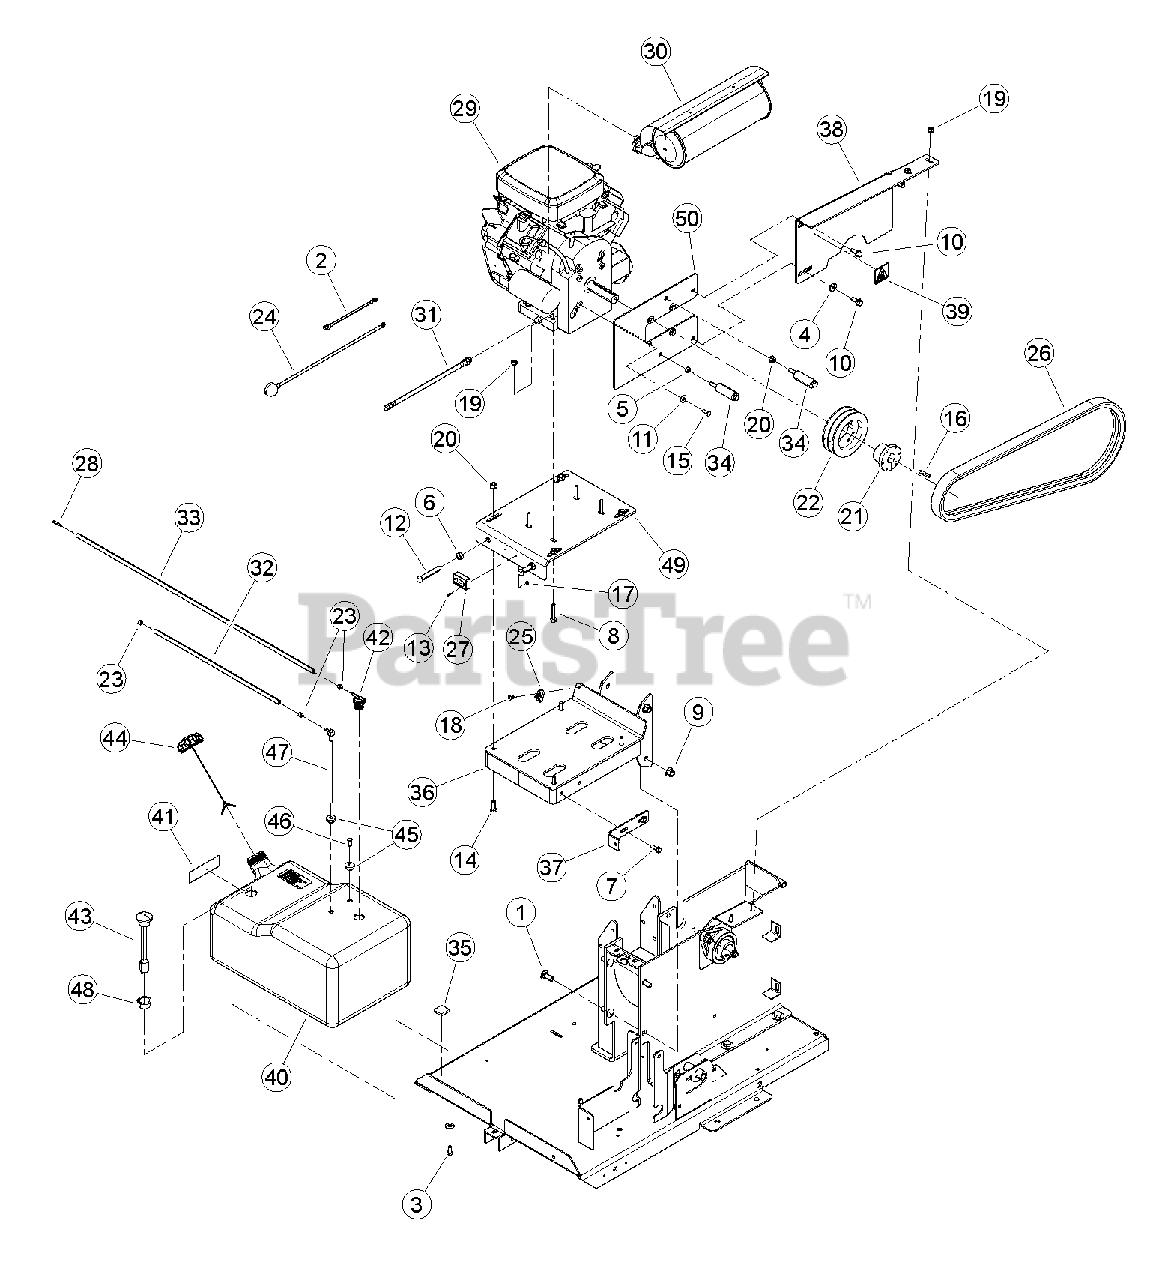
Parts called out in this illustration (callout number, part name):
1	BOLT, 1/2-13 X 1-1/4 GR5 CRG
2	CABLE, 24" NEG (R/R)
3	BOLT, 3/8 X 3/4 GR5 HEX CAPSCREW ZP
4	WASHER, 3/8 FLAT
5	NUT, 3/8" HEX NC ZP
6	NUT, 1/2 NC ZP JAM
7	BOLT, 5/16 X 1 FLANGE NC
8	BOLT, 5/16 X 2 FLANGE NC
9	NUT, 1/2-13 NYLOCK FLANGE
10	BOLT, 3/8 X 1 FLANGE NC
11	WASHER, 5/16 FLAT
12	SETSCREW, 1/2 X 3 SQ HD 1/2 DOG PT
13	SCREW, #6-32 X 3/4 PAN PHP ZP
14	BOLT, 3/8-16 X 1-1/4 GR5 CRG
15	BOLT, 5/16-24 X 3/4" GR5 HHCS ZP
16	KEY, 1/4 SQ X 1-1/2 LG PLAIN
17	NUT, #6-32 NYLON LOCK ZP
18	RIVET, AL BLIND 1/4 X 3/4 DOME HEAD
19	NUT, 5/16-18 NYLOCK FLANGE
20	NUT, 3/8-16 NYLOCK FLANGE
21	BUSHING, SD 1-1/8"
22	SHEAVE, 2B5.2 SDS
23	CLAMP, 15/32 SPRING
24	CABLE, 33" POS (R/R WITH BOOT)
25	CLAMP, CABLE MOUNT
26	BELT, 2BRP67
27	METER, TACH/HOUR
28	FITTING, 3/16" X 1/4" VACUUM
29	ENGINE, 23 HP BRIGGS (FOR SERVICE SEE ENGINE OWNER'S MANUAL OR NEAREST BRIGGS & STRATTON INDUSTRIAL ENGINE DEALER)
30	MUFFLER, BRIGGS 23 HP OIL FILTER SIDE (FOR SERVICE SEE ENGINE OWNER'S MANUAL OR NEAREST BRIGGS & STRATTON INDUSTRIAL ENGINE DEALER)
31	HOSE ASSEMBLY, CRANKCASE DRAIN
32	HOSE, 20" FUEL LINE
33	HOSE, 38" FUEL LINE
34	WELDMENT, BELT GUIDE
35	PAD, FOAM FUEL TANK DAMPER
36	WELDMENT, ENGINE BASE
37	WELDMENT, SHIELD BRACKET
38	ASSEMBLY, BELT GUIDE W/ DECAL
39	DECAL, SHIELD DANGER ISO
40	ASSEMBLY, FUEL TANK
41	DECAL, UNLEADED GASOLINE
42	VALVE, ROLL OVER
43	GAUGE, FUEL LEVEL KELCH 100
44	CAP, NON-VENTED EPA/CARB APPROVED
45	GROMMET, TANK FITTING
46	PLUG, TANK VENT
47	FITTING, TANK FUEL PICK-UP TUBE
48	GROMMET, KELCH 100 GAUGE
49	WELDMENT, ENGINE MOUNT PLATE
50	WELDMENT, BELT SHIELD BRACKET
